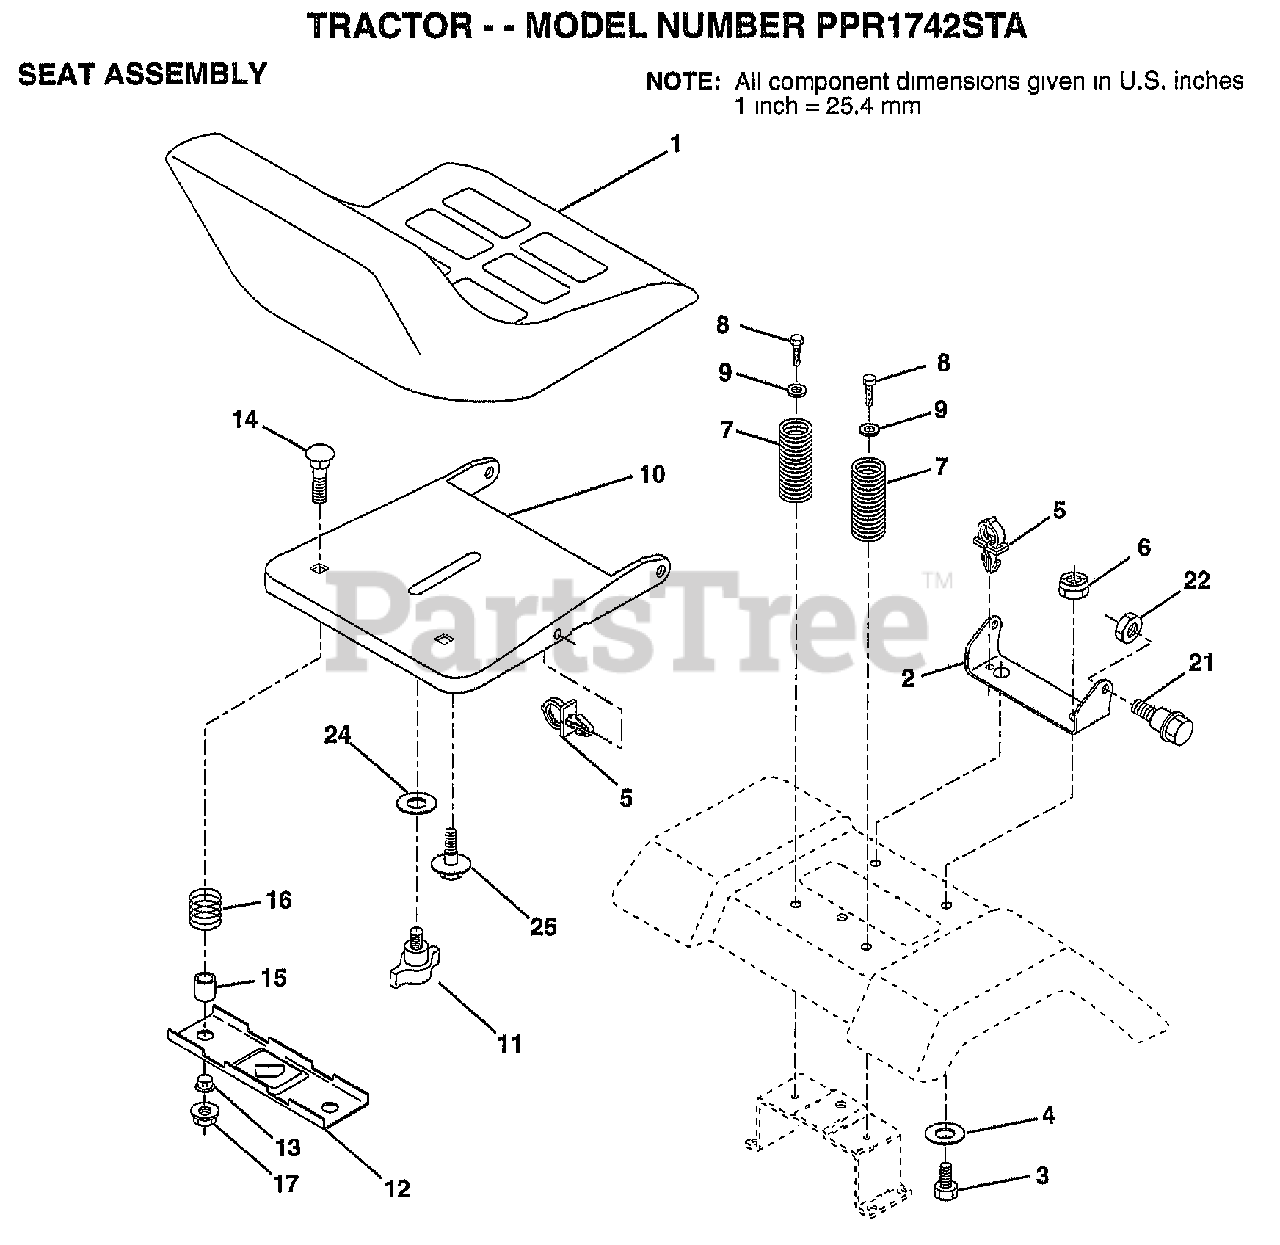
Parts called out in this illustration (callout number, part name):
1	SEAT.2400/1416.BK
2	BRACKET PVT SEAT
3	BOLT
4	WASHER PM
5	CLIP.PUSH-IN.HING
6	NUT
7	SPRING, COMPRESSION, SEAT
8	SCREW GTV
9	WASHER
10	PAN-SEAT
11	KNOB.SEAT.ADJ.WINGNUT
12	BRKT SWITCH
13	BUSHING
14	BOLT-RD HD SQ NK
15	SPLIT SPACER
16	SPRING
21	"BOLT,SHOULDER"
22	NUT
24	WASHER
25	"BOLT,SHOULDER"
